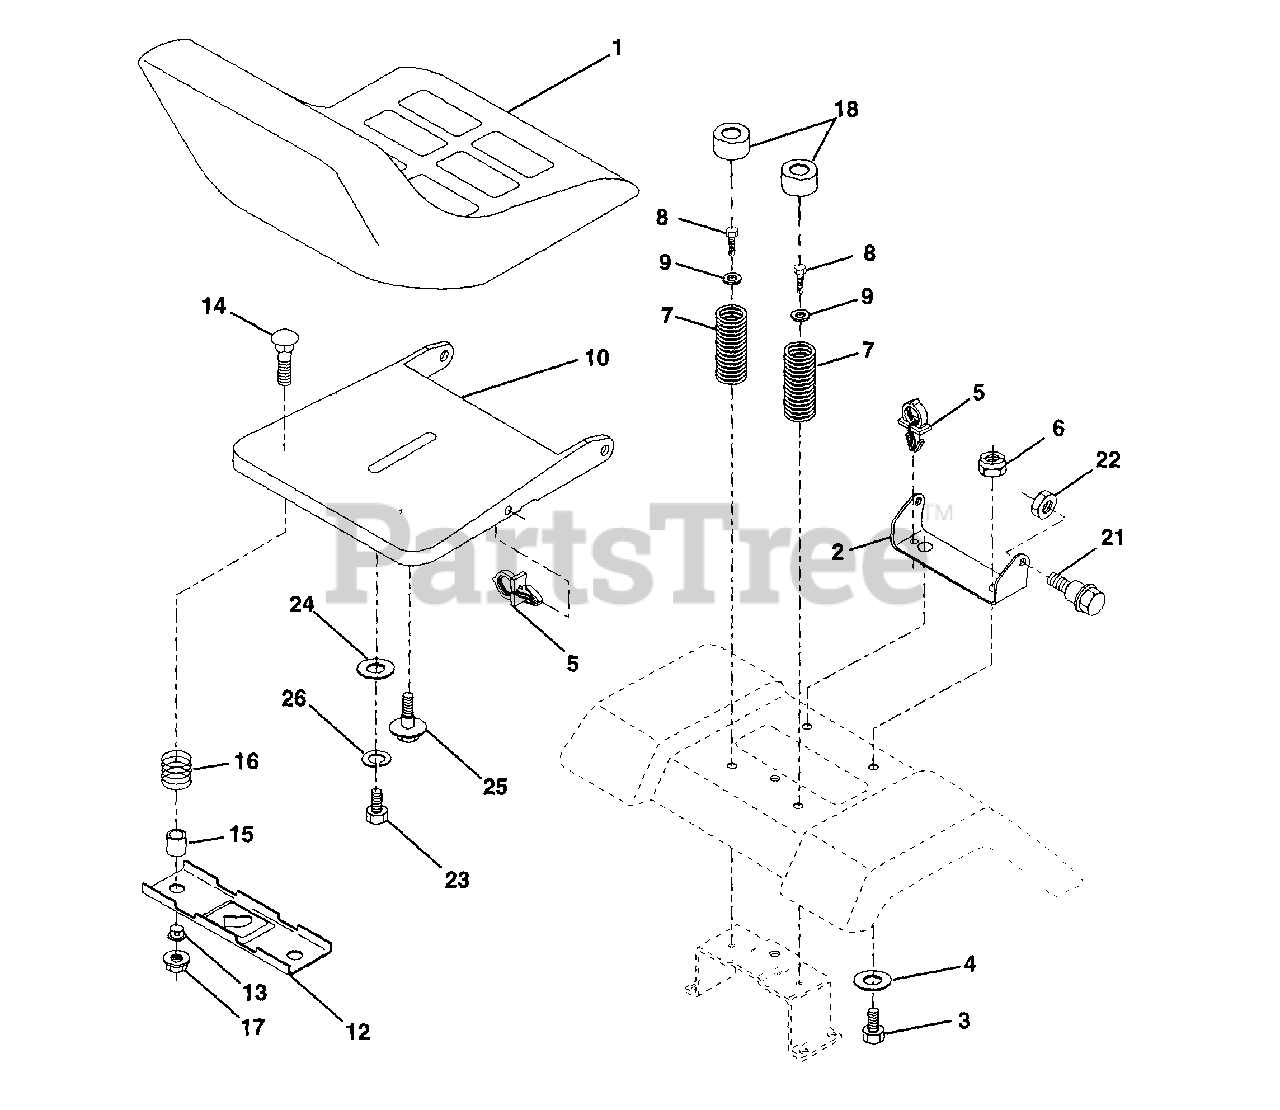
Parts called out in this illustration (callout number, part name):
1	Seat
2	Bracket Pivot Seat 8 720
3	Bolt Fin Hex 3/8-16unc x 1
4	Washer 13/32 x 1 x 10 Ga
5	Clip Push-In
6	Nut Hex w/Ins. 3/8-16 Unc
7	Spring Seat Cprsn 2 250 Blk Zi
8	Screw Thdrol 3/8-16 x 1 Ty-tt
9	Washer 13/32 x 1 x 14 Ga.
10	Pan Seat
12	Bracket Mounting Switch
13	Bushing Snap Blk Nyl 50 Id
14	Bolt Rdhd Sqnk 1/4-20 x 1-3/8
15	Spacer Split 28 x .88 Zinc
16	Spring Cprsn Plate
17	Nut Lock 1/4 Lge Flg Gr 5 Zinc
18	Cap Spring Seat
21	Bolt Shoulder 5/16-18 Unc
22	Nut Hex Lock W/Ins 5/16-18
23	Bolt, Hex Head, Fin 1/2-13 x 7/8 Grade 5
24	Washer 17/32 x 1-3/16 x 12 Ga.
25	Bolt Shoulder 5/16-18 x 62
26	Washer Lock
